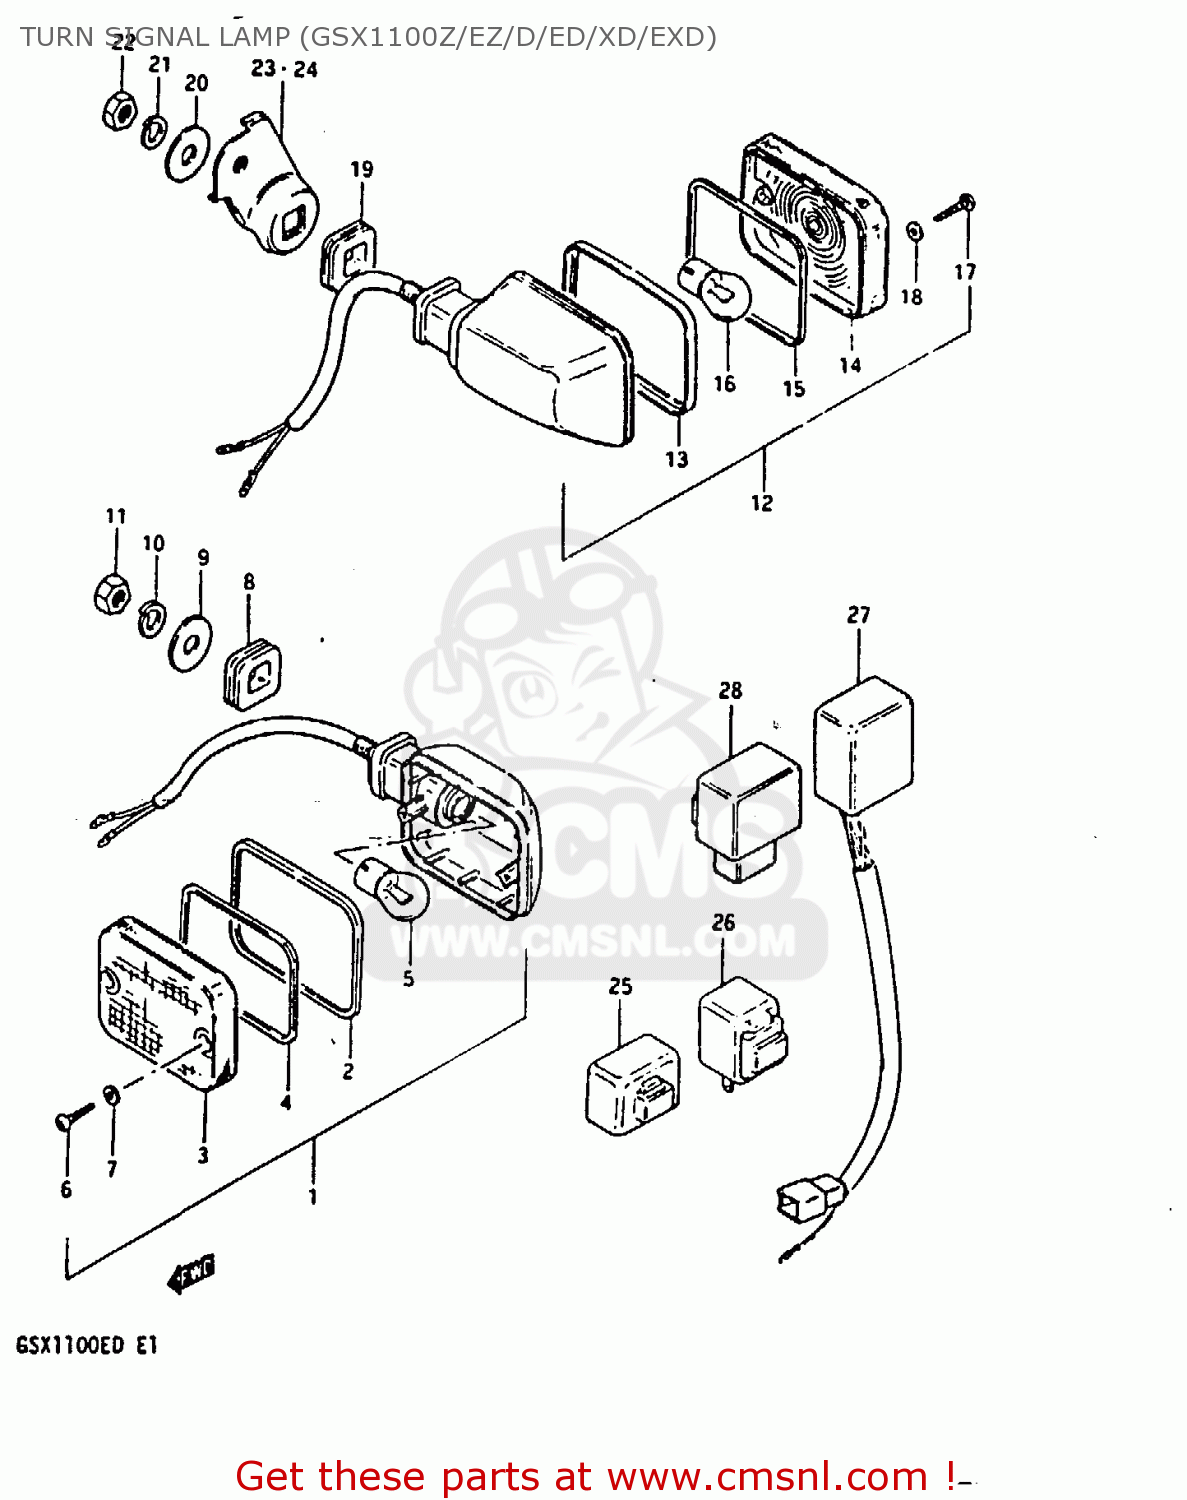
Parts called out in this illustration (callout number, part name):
1	LAMP ASSY,FR T
2	RIM
3	LENS
4	GASKET (NAS)
5	BULB(12V21W)
6	SCREW
7	GASKET (NAS)
8	CUSHION
9	WASHER (10.5X30X2.3)
10	LOCK WASHER
11	NUT
12	LAMP, REAR TURN SIGNAL
13	RIM
14	LENS
15	GASKET (NAS)
16	BULB(12V21W)
17	SCREW
18	GASKET (NAS)
19	CUSHION
20	WASHER (10.5X30X2.3)
21	LOCK WASHER
22	NUT
23	BRACKET,REAR TURN SIGNAL
24	BRACKET,RR TURNSIGNAL LAMP,L
25	RELAY ASSY,TURNSIGNAL
27	UNIT,TURN SIGNAL CONTROL
28	UNIT,TURN SIGNAL CONTROL
